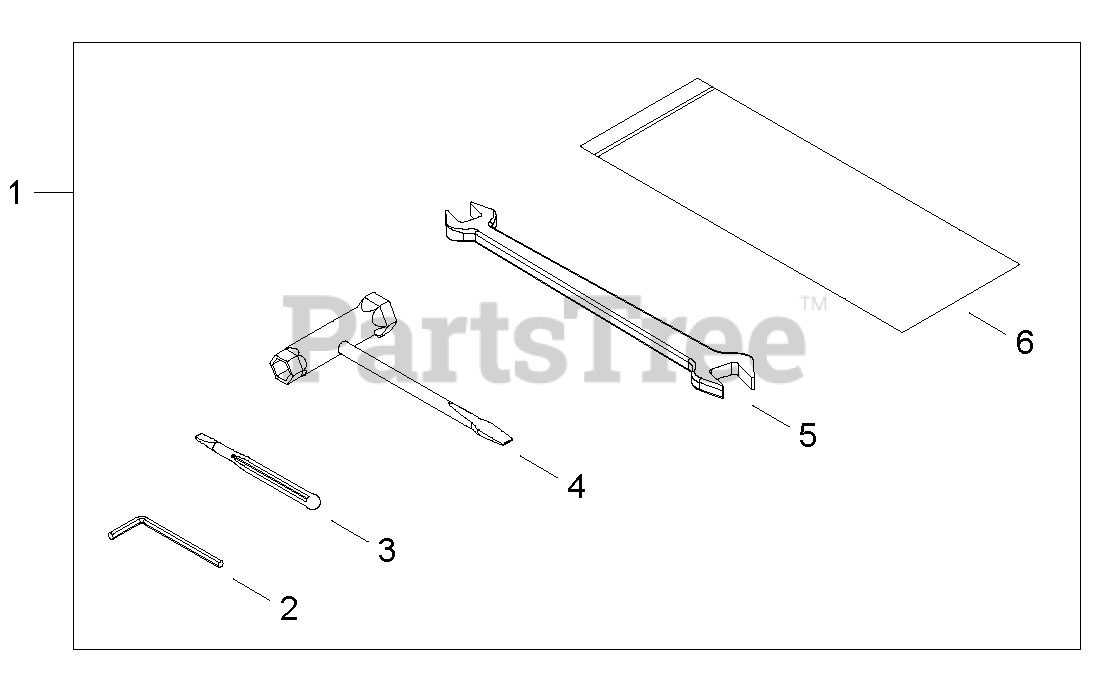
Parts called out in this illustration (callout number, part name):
2	HEX KEY - 4mm
3	SCRAPER
4	T-WRENCH - 13X19mm
5	SPANNER - 8X10mm
6	BAG, TOOL
13-1	TOOL KIT
